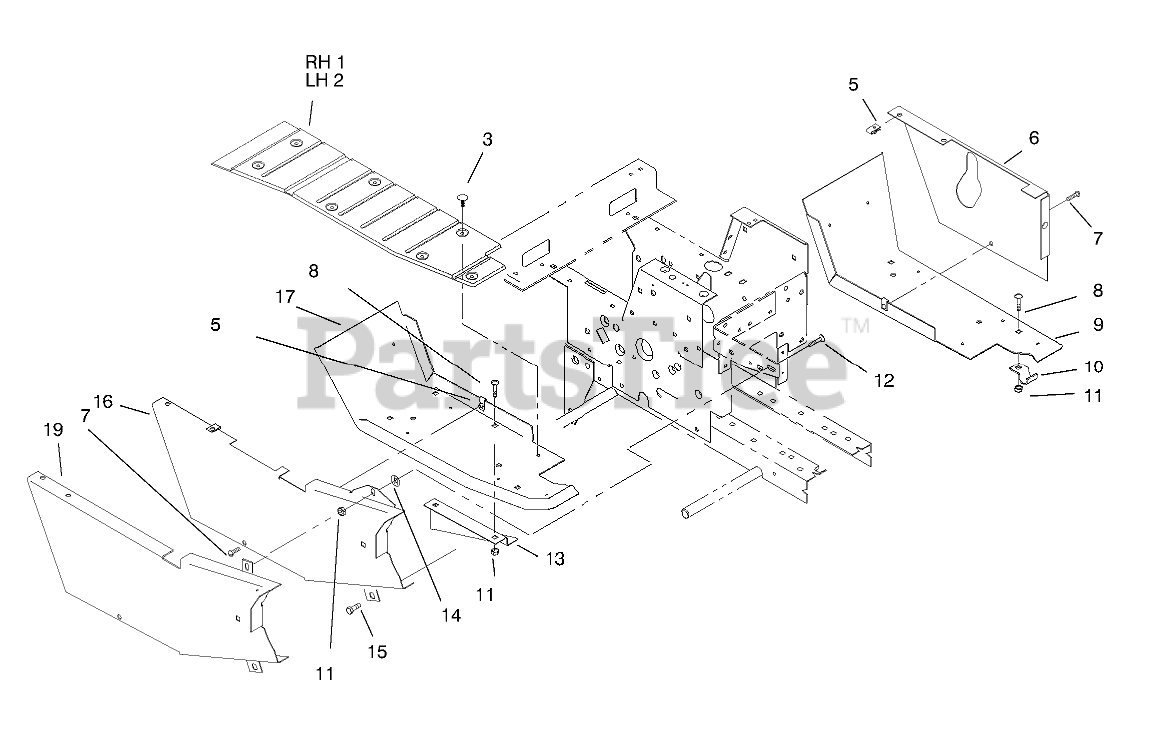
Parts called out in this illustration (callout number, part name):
1	PAD-FOOT RH
2	PAD-FOOT LH
3	FASTENER-PANEL
6	COVER-LH
7	SCREW-PPH
8	BOLT-CARR
9	FOOTREST-LH
10	BRACKET
11	NUT-LOCK, NI
12	BOLT-CARR
13	GUIDE-LOWER BELT
14	NUT-PUSH
15	Bolt
17	FOOTREST-RH
19	Belt Guard
